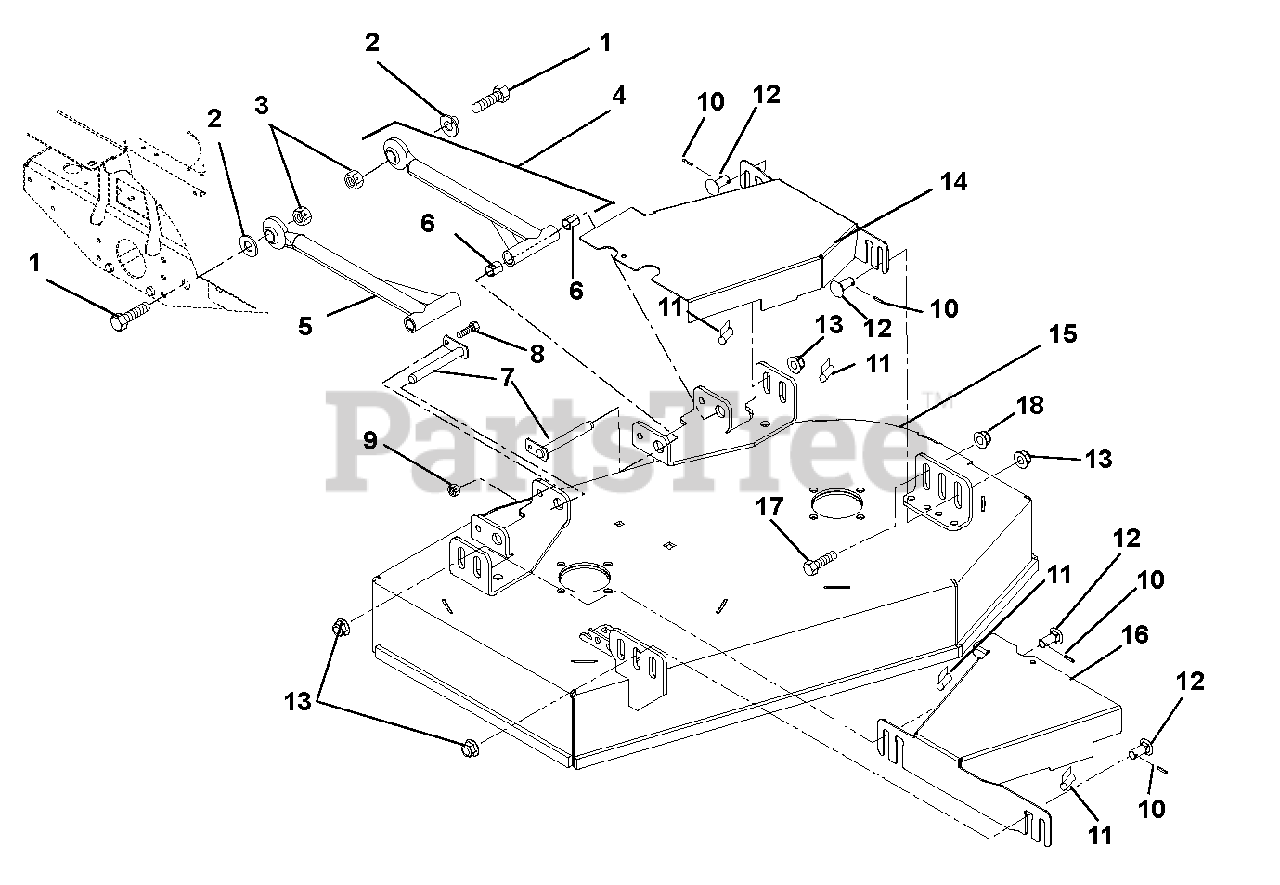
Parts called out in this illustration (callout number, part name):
1	Bolt, Hex .875-9 x 3.00
2	Bushing, Sleeve .875 x 1.25 x .531
3	Nut, Locking Center .875-9
4	Assembly, Mower Mounting (Includes Items 5 and 6)
5	Arm, Mower Mounting
6	Bearing, .75 x .875 x 1.00
7	Weldment, Mower Mounting Pin
8	Bolt, Hex .38-16 x 1.00
9	Nut, Nyloc Flange 3/8-16
10	Pin, Roll .125 x .75
11	Seal, Trim-LOK Bulk .06 Bubble
12	Bolt, Round Head Square Neck .50-13 x 1.25 SPL
13	Nut, Nyloc Flange .50-13
14	Weldment, Belt Guard 34" Left Hand
15	Weldment, 34" Mower Deck, Rear Discharge
16	Weldment, Belt Guard 34" Right Hand
17	Bolt, Round Head Square Neck .31-18 x .75 Grade 5 (991301)
18	Nut, Locking Nylon Flange .31-18 YZ (991301)
